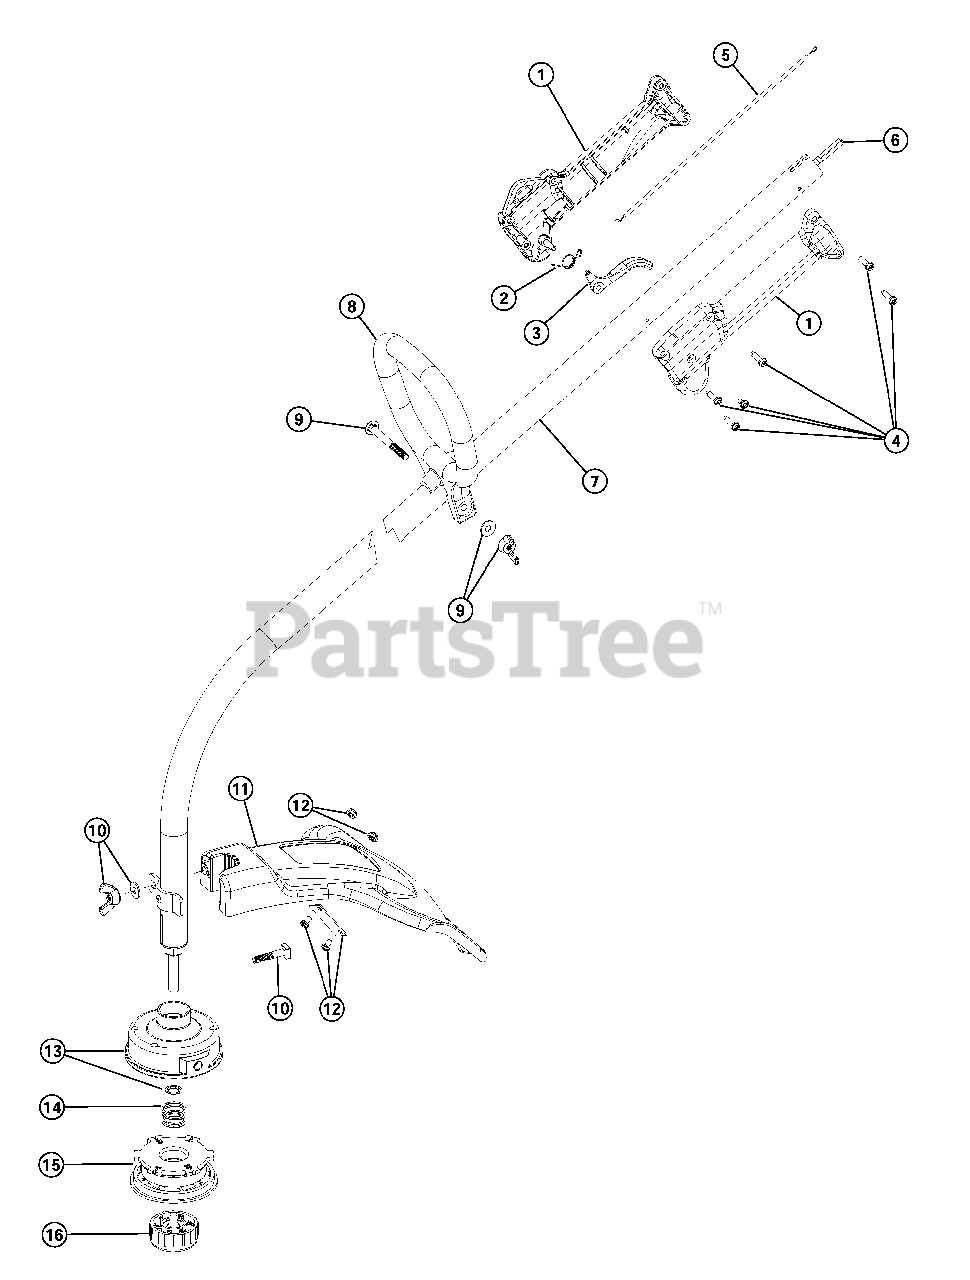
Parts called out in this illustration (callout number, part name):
1	Throttle Housing and Trigger Assembly
2	Throttle Trigger Spring
3	Throttle Trigger
4	Throttle Housing Screws
5	Throttle Cable
6	Flexible Drive Shaft
7	Drive Shaft Housing Assembly
8	D-Handle Assembly
9	D-Handle Hardware
10	Guard Mounting Hardware
12	Blade Assembly
13	Outer Reel w/Retainer
14	Spring
15	Inner Reel
16	Bump Knob
